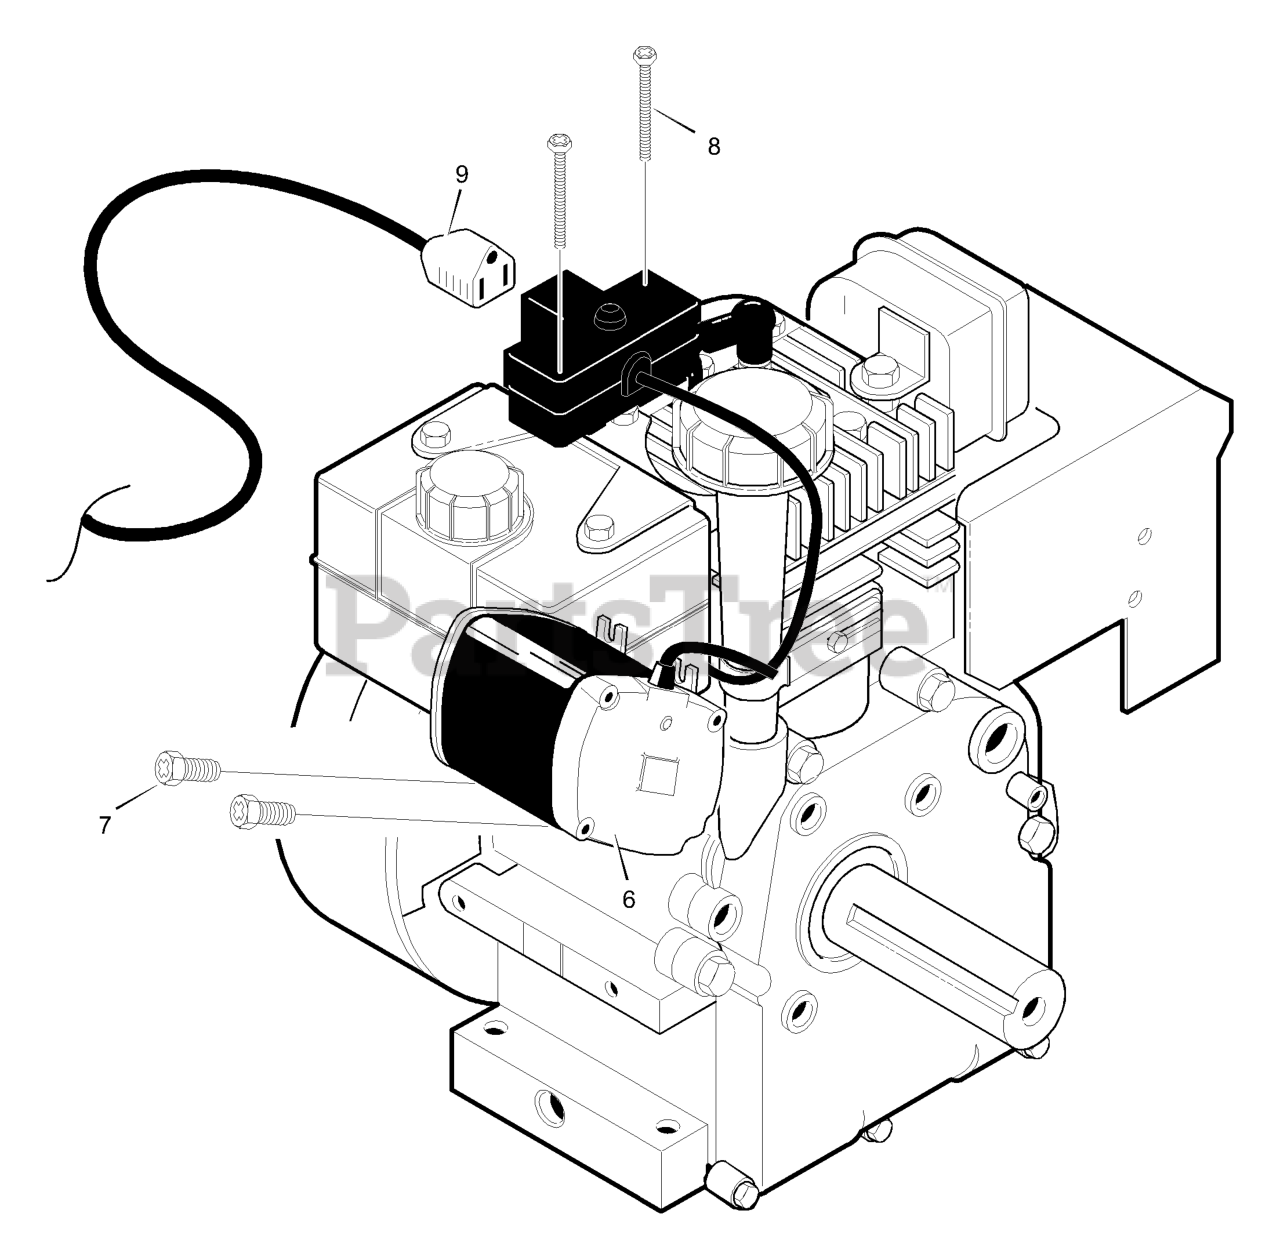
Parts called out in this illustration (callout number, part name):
6	MOTOR, STARTER
8	SCREW
9	CORD, Electric, 10FT. 110V
